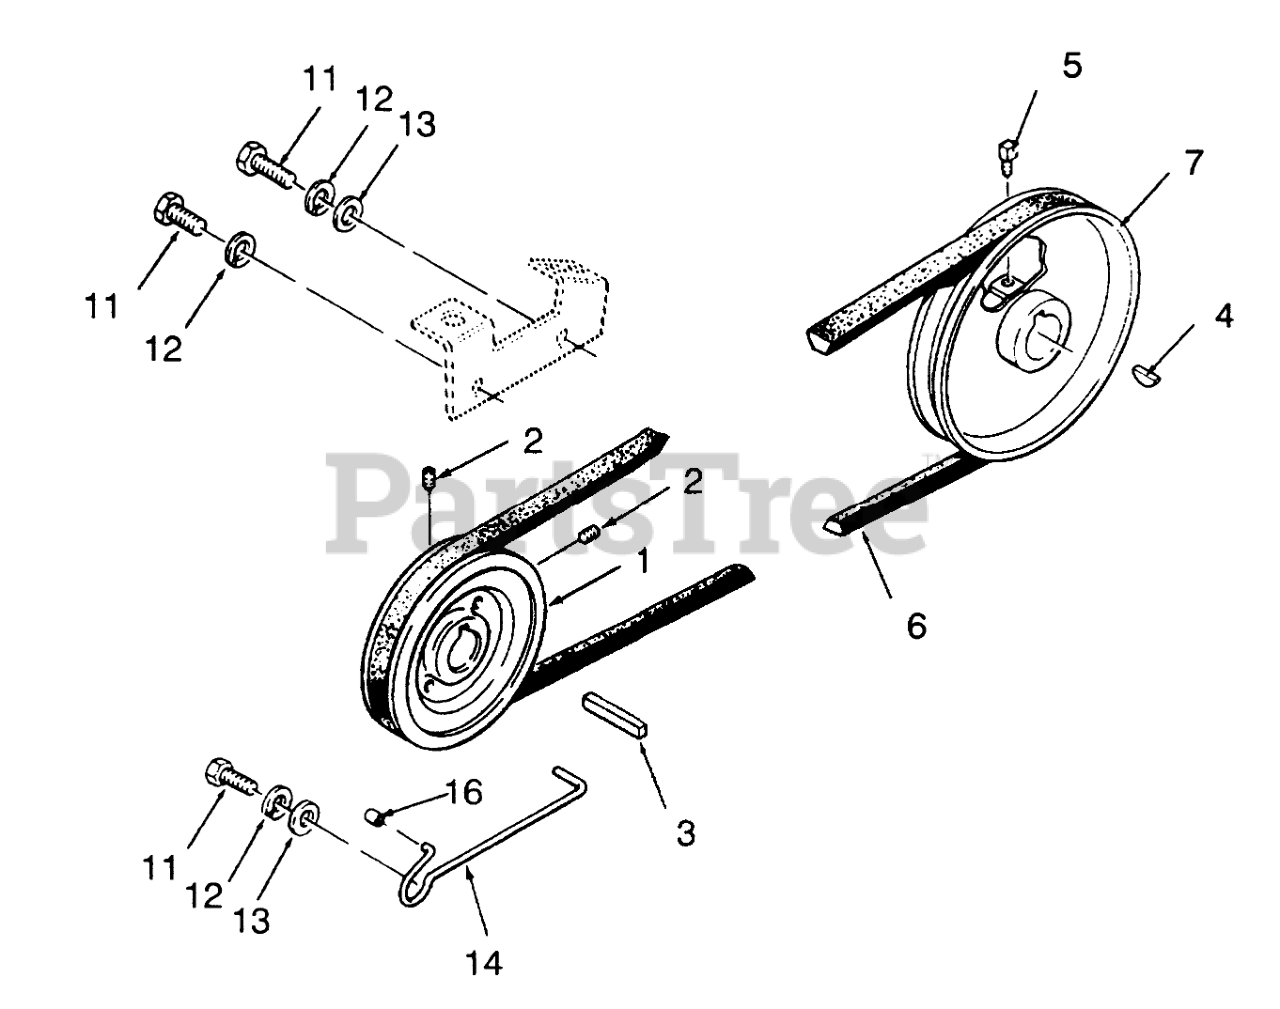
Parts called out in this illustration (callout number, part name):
1	PULLEY
2	SCREW-SET, HSH
4	KEY-HI PRO
5	SCREW-SQH
6	V BELT
7	PULLEY-TRANSMISSION
11	Bolt
12	WASHER-LOCK
13	WASHER-FLAT
14	GUIDE BELT
